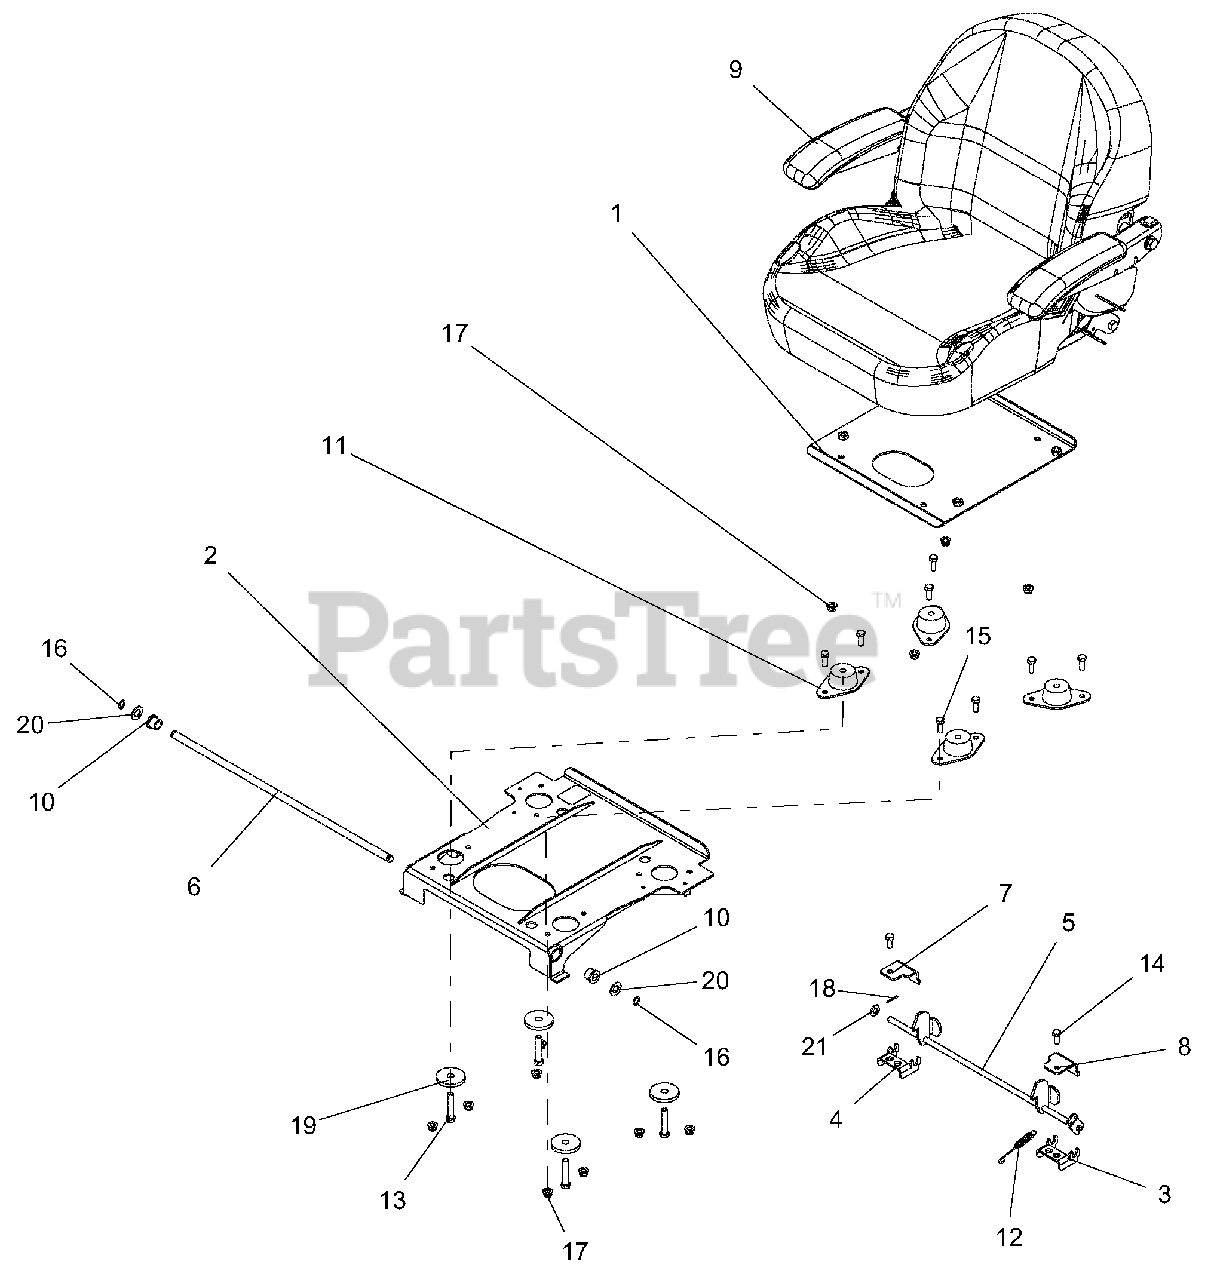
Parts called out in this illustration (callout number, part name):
1	WLDMT, SEAT MOUNTING PLATE-BLACK
2	WLDMT, PT ISOLATOR MTG PLATE-BLACK
3	WLDMT, PT/PT100 LH SEAT LATCH MOUNT-BLACK
4	WLDMT, PT/PT100 RH SEAT LATCH MOUNT-BLACK
5	WLDMT, PRO-TURN SEAT LATCH-BLACK
6	SHAFT, PT/PT100 SEAT PIVOT
7	MOUNT, PT/PT100 RH TOP SEAT LATCH-BLACK
8	MOUNT, PT/PT100 LH TOP SEAT LATCH-BLACK
9	SEAT, NON-SUSPENSION
10	BSHG, SHLDR EP .358-16X.30 HEX YZ
11	MOUNT, FAIL-SAFE COMPRESSION
12	SPRG, EXTENSION
13	BLT-HEX .38-16X2.00 GR5 YWZC
14	BLT-HEX .31-18X.75 GR5 YWZC
15	BLT-HEX .31-18X.875 GR5 YWZC
16	RG-RTNG-EXT .500x.050
17	NUT-LK-NYL-FLG .31-18 YWZC
18	@PIN-CTR .09X.75 EXTPRSQCT YWZ
19	WSHR-FL-STL .469X2.00X.25 YWZC
20	WSHR-FL-STL .531X1.000X.063 YWZC
21	WSHR-FL-STL.406X.812X.065 YWZ
